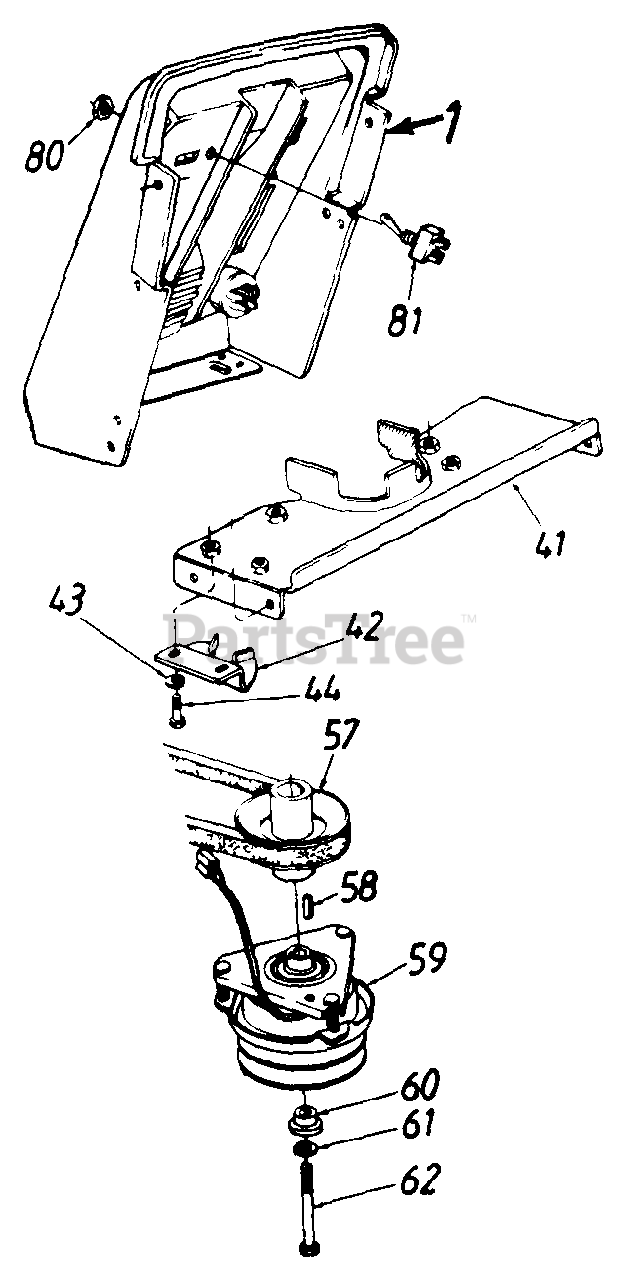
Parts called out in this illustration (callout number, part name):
1	Dash Panel
41	Belt Guard Brkt.
44	Hex Bolt 5/16-18 x 75" Lg (Gr 5)
57	Engine Pulley
58	Sq. Key 1/4" x 1" Lg.
59	Electric Clutch
60	Shld. Spacer
61	L-Wash 7/16" I.D.
62	Hex Bolt 7/16-20 x 3.75" Lg.
